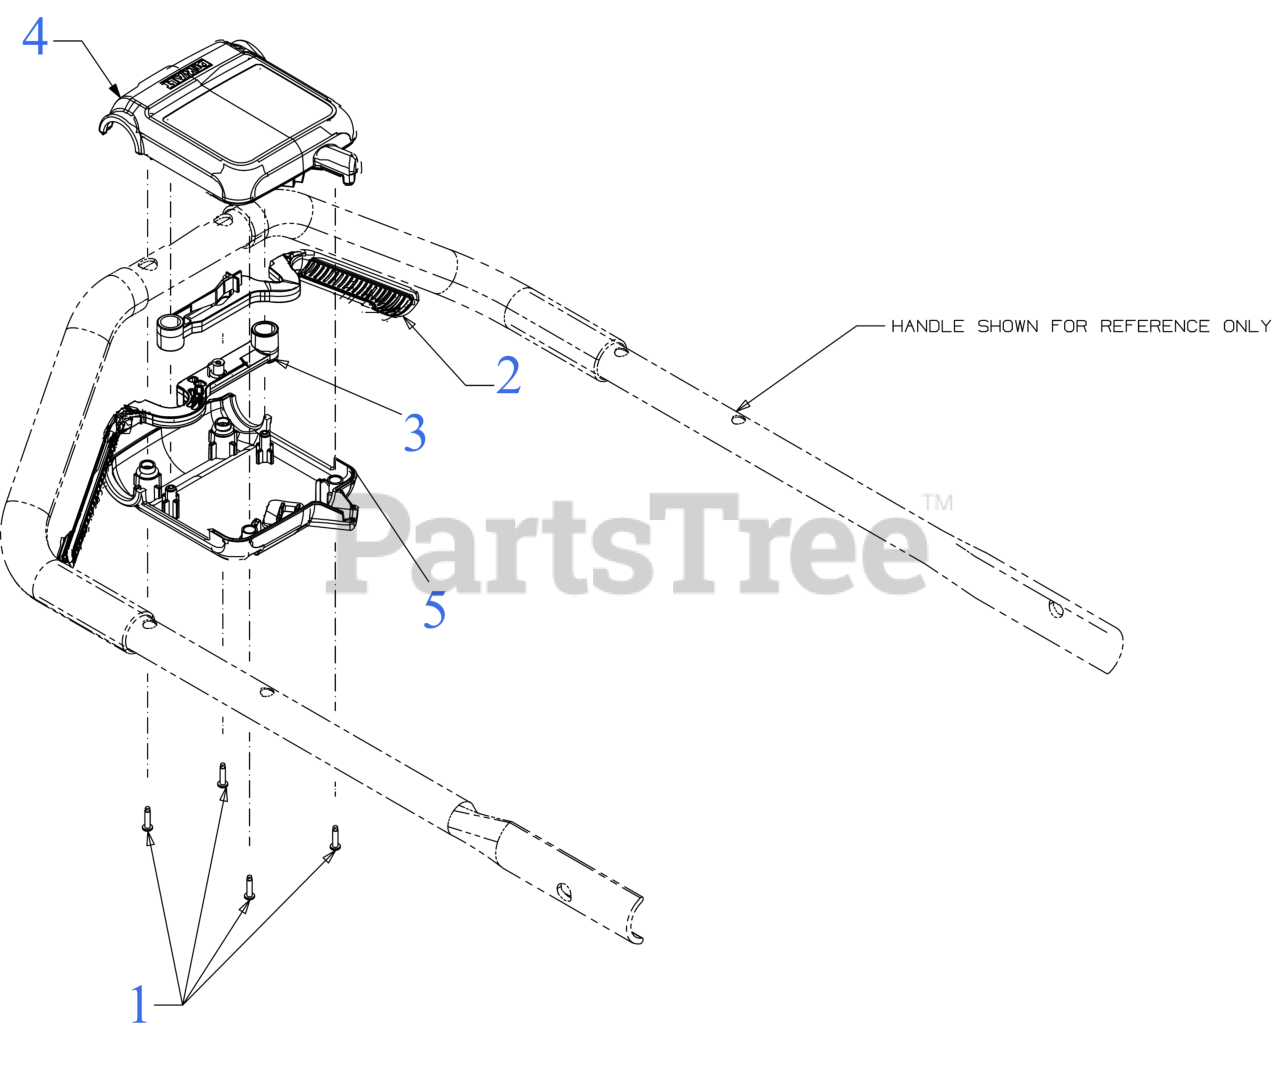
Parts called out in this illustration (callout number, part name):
1	SCREW-TAP PLASTIC #6-19 X 0.62
2	CONTROL LEVER (LH)
3	CONTROL LEVER (RH)
4	HSG:CTRL:UPR:DEW RWD W/LBL
5	HSG:CTRL:LWR:DEWALT RWD
